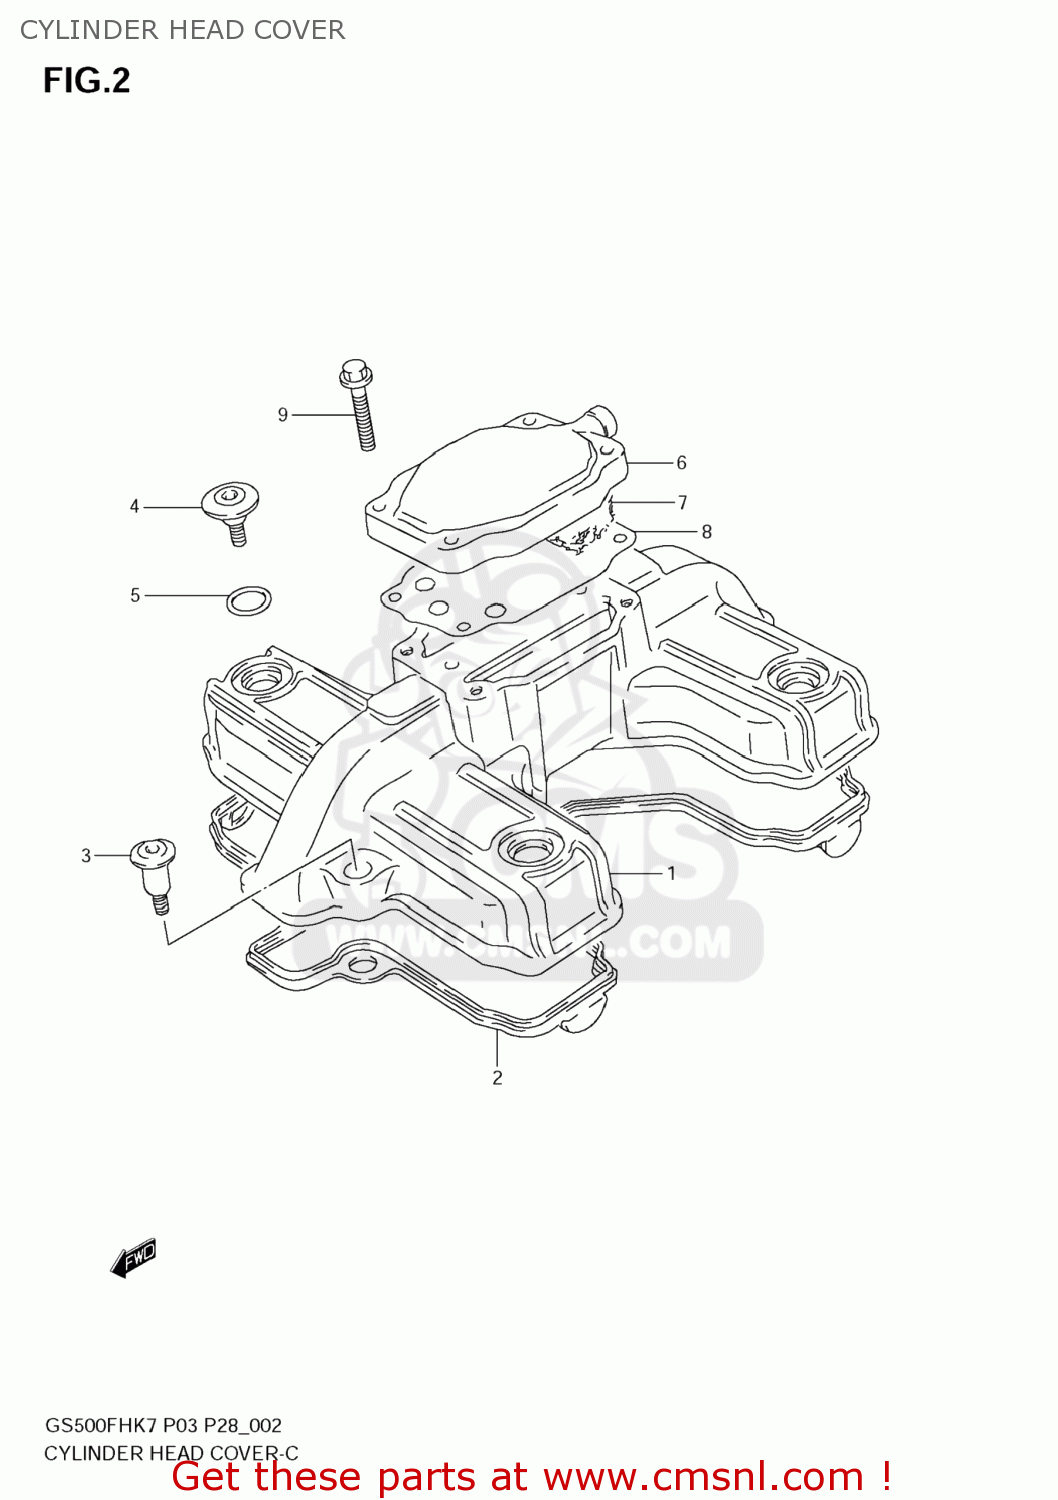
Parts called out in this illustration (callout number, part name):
1	COVER,CYLINDER HEAD
2	GASKET,CYL HEAD COVER (NAS)
3	BOLT(7X31)
4	BOLT(7X17.5)
5	O RING(D:1.9,ID:14.5)
6	COVER,BREATHER
7	SEPARATOR,OIL BREATHER COVER
8	GASKET,BREATHER COVER (NAS)
9	BOLT
